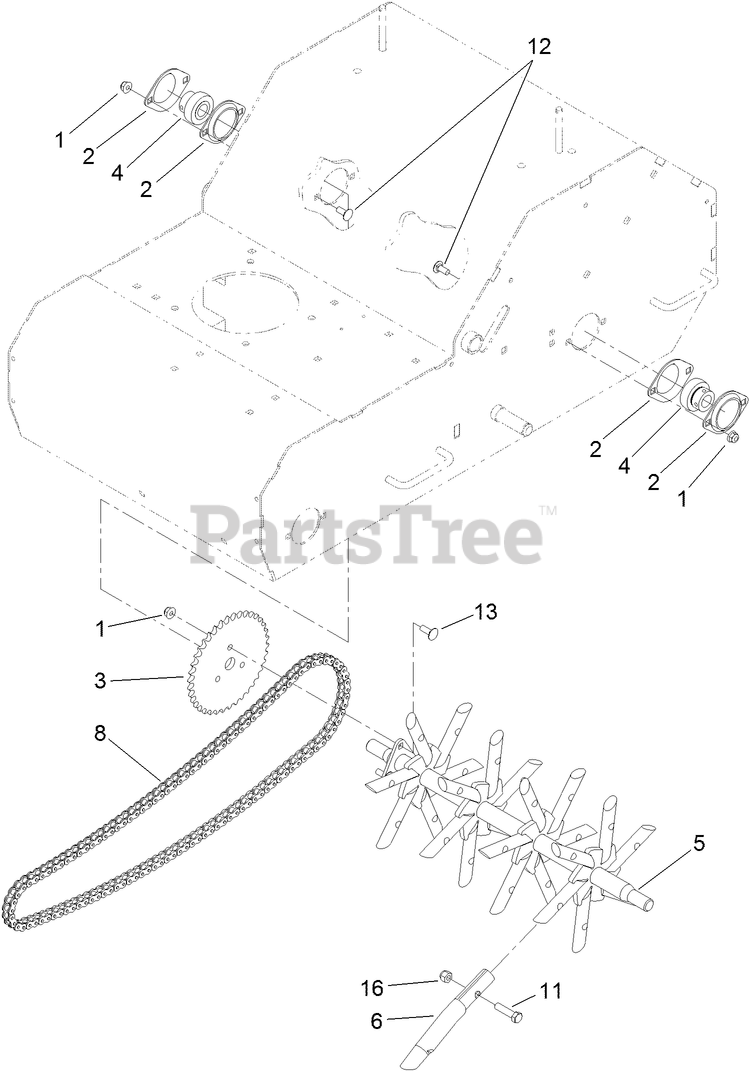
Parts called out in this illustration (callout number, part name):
1	NUT-HF, NI
2	FLANGE-BEARING
3	SPROCKET
4	BEARING-LOCK, COLLAR
5	WHEEL-TINE
6	TINE-CORING
11	SCREW-HH
12	SCREW-CARR
13	BOLT-CARR
16	NUT-LOCK, NI
